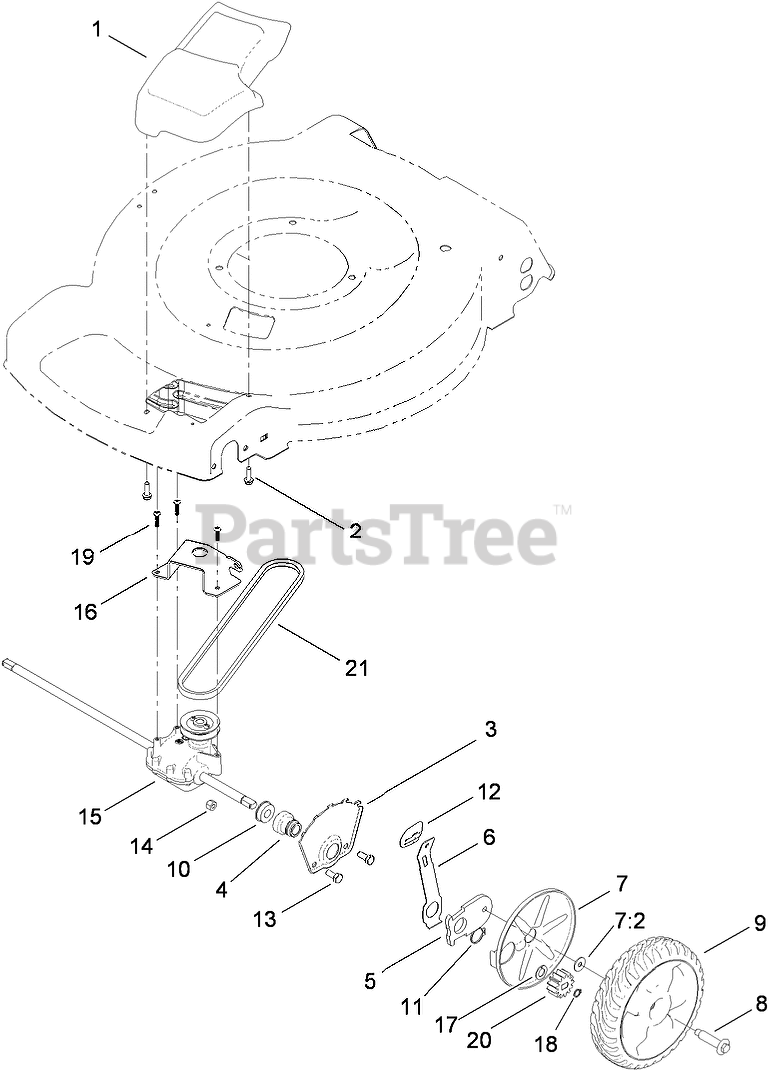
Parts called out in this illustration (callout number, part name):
1	COVER-BELT
2	SCREW-HWH
3	PLATE-HOC, FRONT
4	RETAINER-BEARING, HOC
5	ARM-PIVOT, FRONT
6	Arm-Spring
7	WHEEL COVER ASM
7:2	WASHER-STEPPED
8	BOLT-SHOULDER
9	8 INCH WHEEL ASM
10	BEARING-BALL
11	RING-RETAINING
12	Knob-Lever, HOC
13	SCREW-HH
14	NUT-LOCK, NI
15	TRANSMISSION ASM
16	BRACKET-TRANSMISSION
17	WASHER-THRUST
18	RING-RETAINING
19	SCREW-PLASTITE
20	GEAR-PINION, 13T
21	V-BELT
